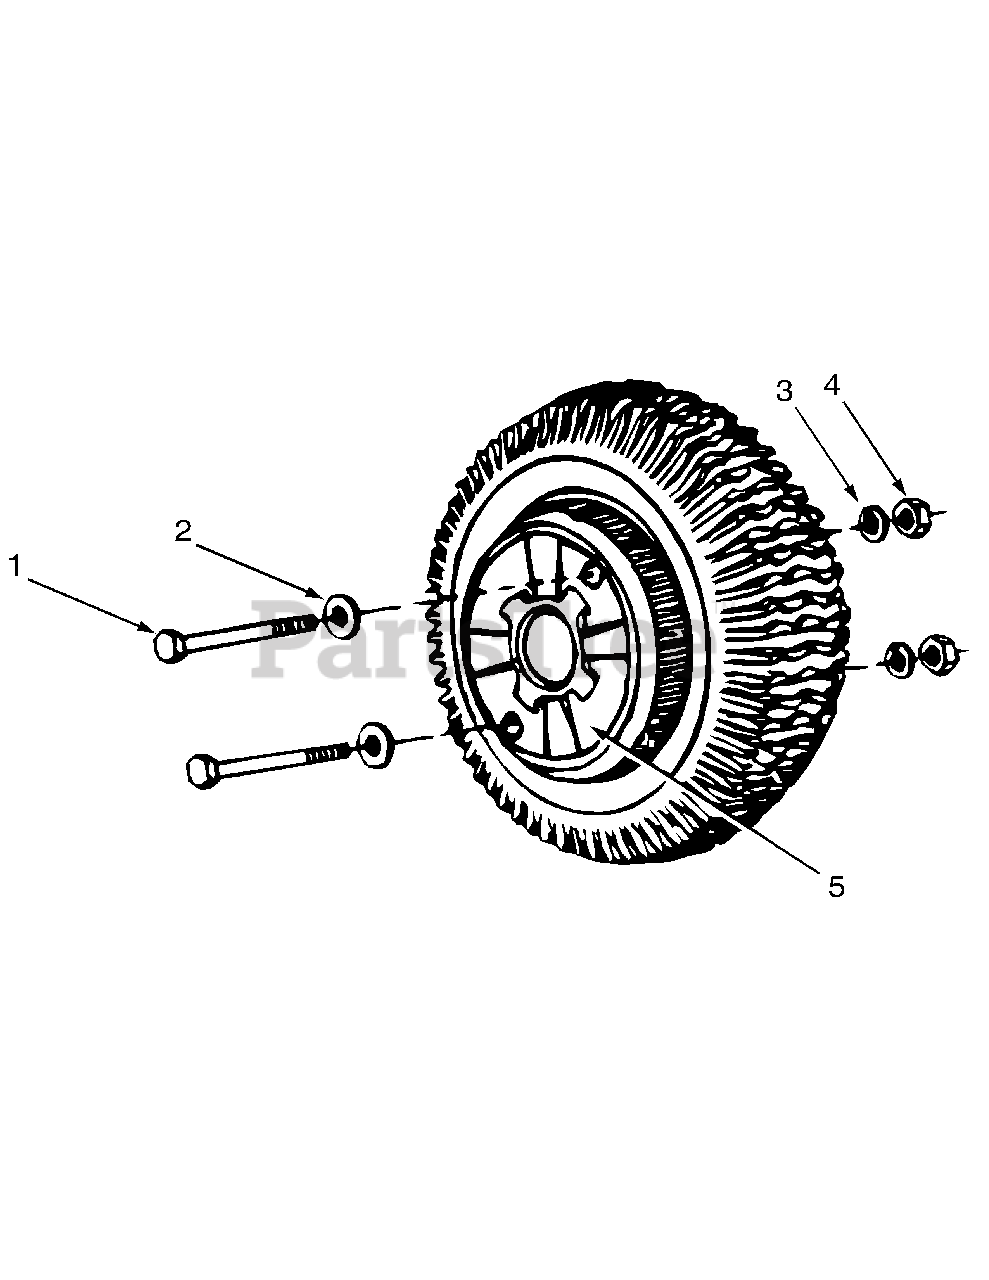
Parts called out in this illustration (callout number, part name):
1	Hex Screw, 3/8-16 x 7.50
2	Flat Washer, 3/8
3	Lock Washer, 3/8
4	Hex Nut, 3/8-16
5	Wheel Weight
